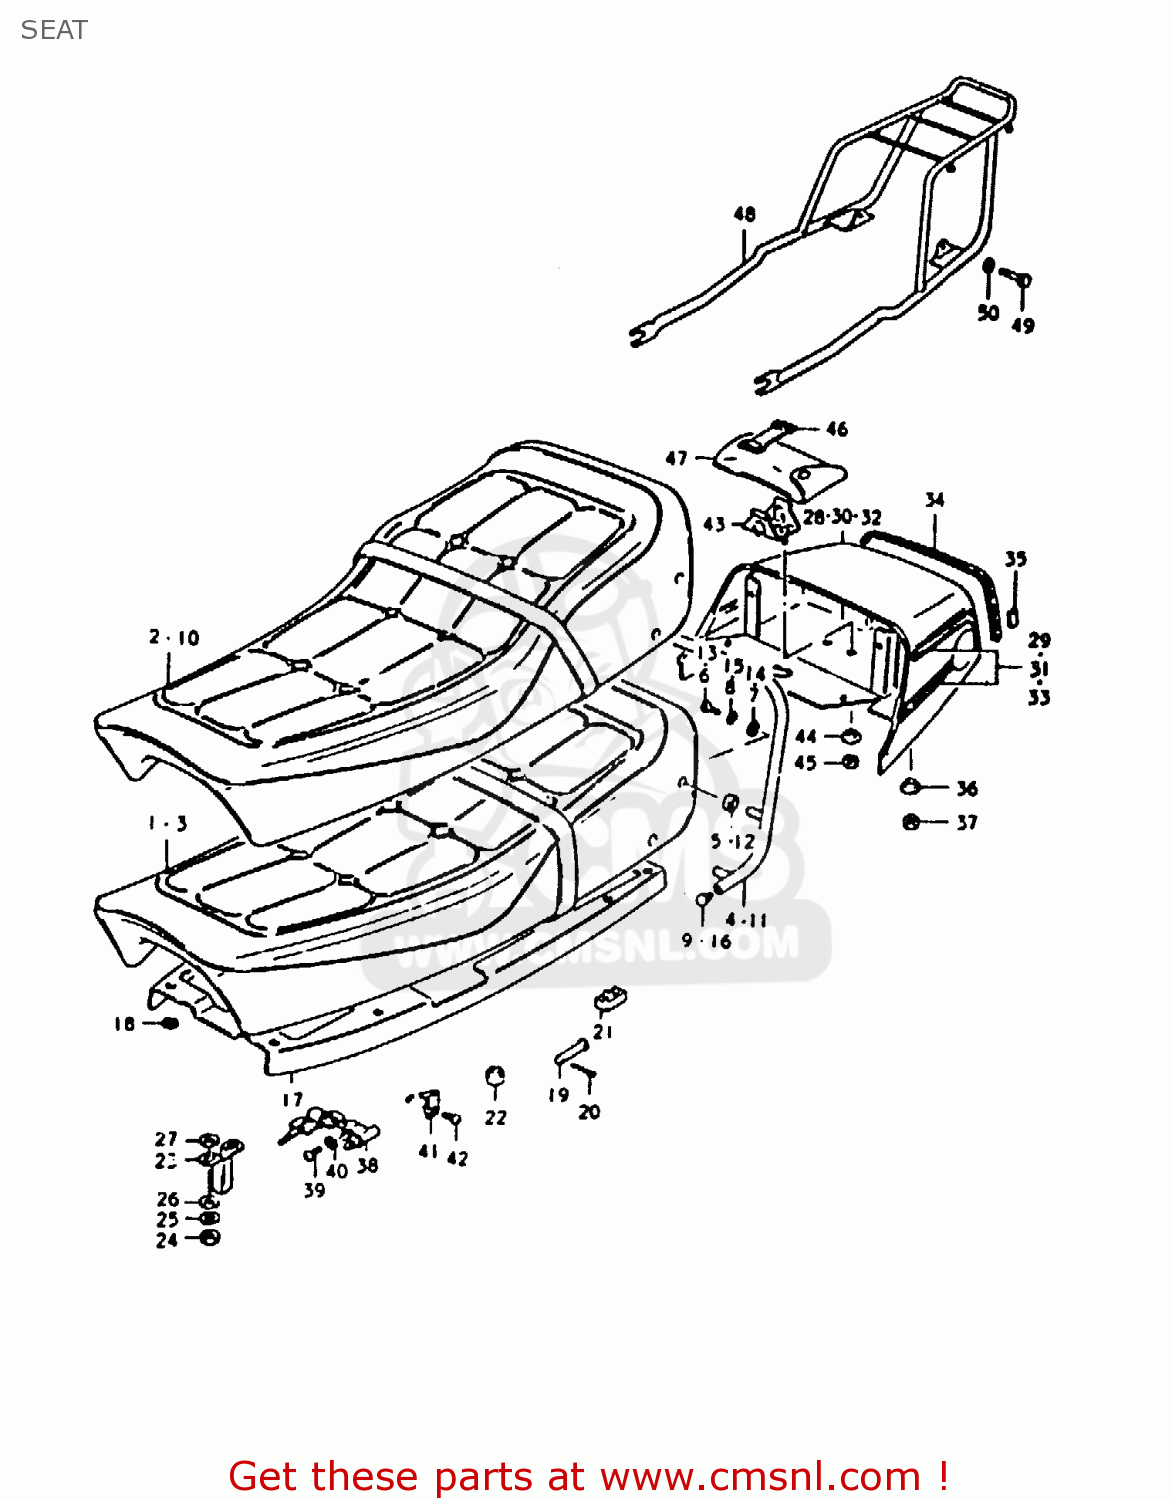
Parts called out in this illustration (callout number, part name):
2	SEAT, STEP TYPE (WITH BAND)
3	SEAT ASSEMBLY
4	HANDLE,PILLION RIDER
5	CUSHION
6	BOLT
7	WASHER
8	LOCK WASHER
9	END,SHEET HANDLE
10	SEAT ASSEMBLY
11	HANDLE,PILLION RIDER
12	CUSHION
13	BOLT
14	WASHER
15	LOCK WASHER
16	END,SHEET HANDLE
17	PLATE, SEAT LOWER (RED)
18	NUT
19	PIN
20	PIN
21	CUSHION
22	CUSHION
23	STRIKER,SEAT LOCK
24	NUT
25	LOCK WASHER
26	WASHER
27	WASHER (6.5X20X1.2)
28	COVER, SEAT TAIL (RED)
29	TAPE SET
30	COVER, SEAT TAIL (BLUE)
31	TAPE SET
32	COVER, SEAT TAIL (BLACK)
33	TAPE SET
34	GROMMET
35	CLIP,SEAT TAIL COVER M
36	WASHER
37	NUT 6MM
38	LOCK ASSY,SEAT
39	SCREW
40	LOCK WASHER
41	SPRING,HELMET HOLDER
42	SCREW
43	HOLDER,TOOL
44	WASHER
45	NUT
46	BAND
47	TOOL SET
48	CARRIER
49	BOLT
50	WASHER
